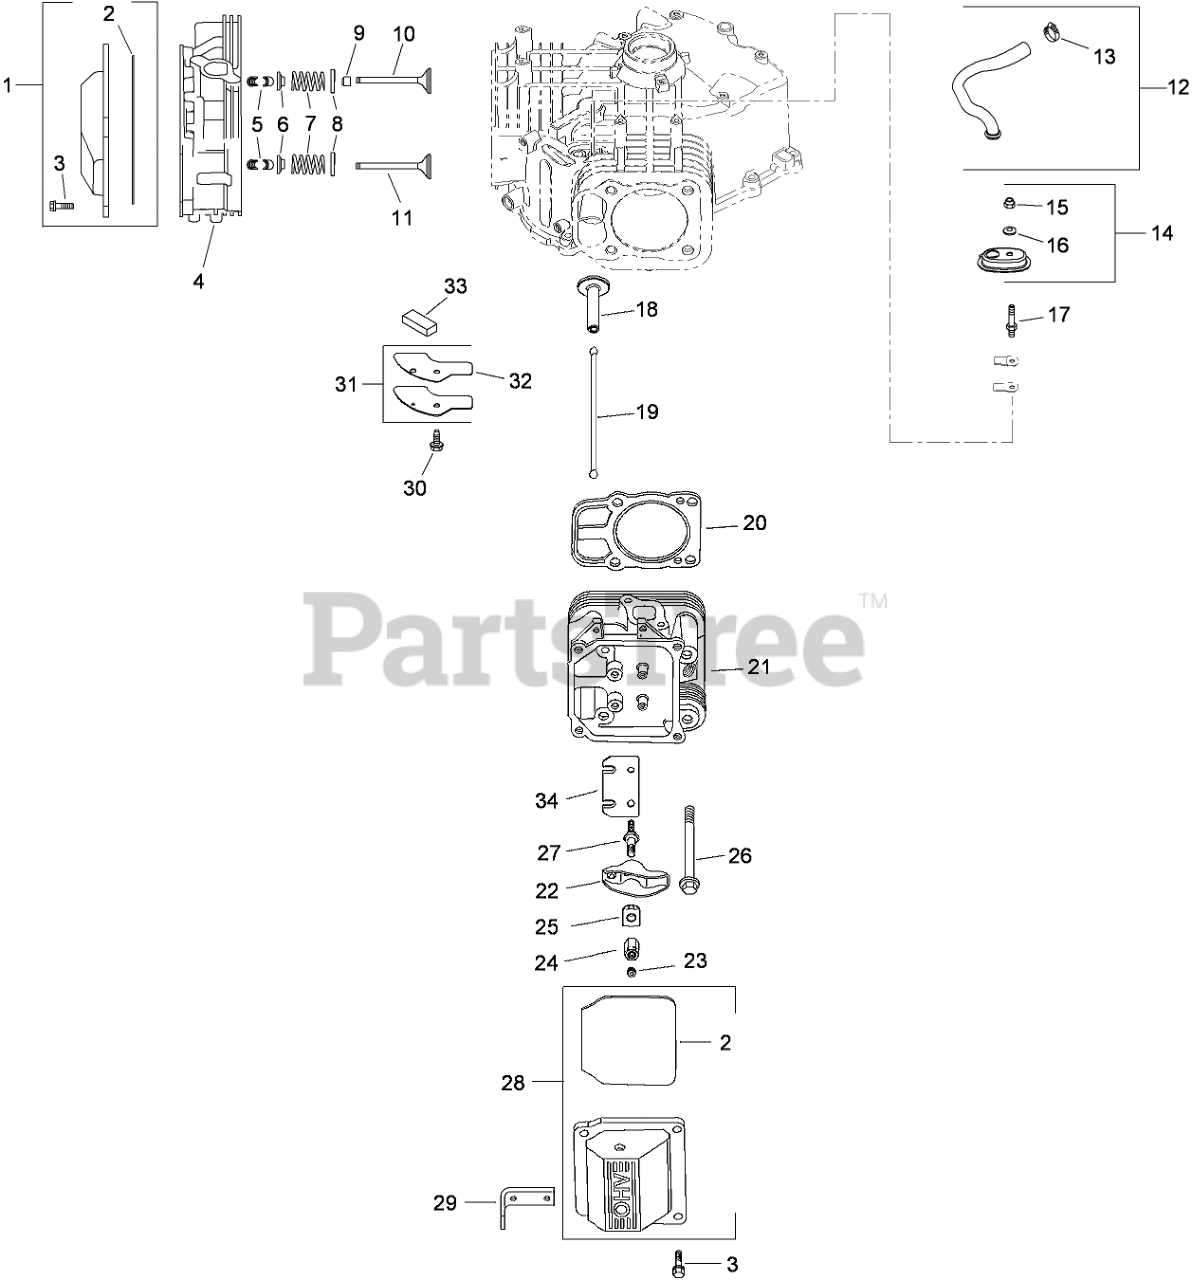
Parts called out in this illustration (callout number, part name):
1	PLAIN ROCKER COVER KIT (INCLUDES 2QTY 1], 3QTY 4])
2	O-RING (VALVE COVER)
3	SCREW-FLANGE (M6X1.0X30)
4	CYLINDER HEAD No.1 ASM (INCLUDES 26 QTY 4] and 20)
5	RETAINER KIT
6	CAP-SPRING, VALVE
7	SPRING-VALVE
8	RETAINER-SPRING
9	SEAL-STEM, VALVE
10	VALVE-INTAKE (STD)
11	VALVE-EXHAUST (STD)
12	BREATHER HOSE KIT (INCLUDES 13 QTY 1])
13	CLAMP-HOSE, SPRING (1/2)
14	BREATHER HOUSING KIT (INCLUDES 15, 16)
15	NUT-LOCK (M5X.8)
16	WASHER-SEALING
17	STUD-COVER, BREATHER
18	Tappet
19	ROD-PUSH
20	CYLINDER HEAD GASKET KIT (INCLUDES HEAD MOUNTING HARDWARE and 24 041 49-S, 24 153 27-S)
21	CYLINDER No.2 HEAD ASM (INCLUDES 26 QTY 4] and 20)
22	ARM-ROCKER
23	NUT (M10X0.75 )
24	SCREW-SET
25	PIVOT-ARM, ROCKER
26	SCREW-FLANGE (M10X1.5X90)
27	STUD-ROCKER
28	BREATHER VALVE COVER KIT (INCLUDES 2 QTY 1])
29	STRAP-LIFTING
30	SCREW-FLANGE, THREAD FORMING (M6X1.0X16)
31	BREATHER COVER KIT (INCLUDES 32)
32	GASKET-COVER, BREATHER
33	FILTER-BREATHER
34	PLATE-GUIDE
